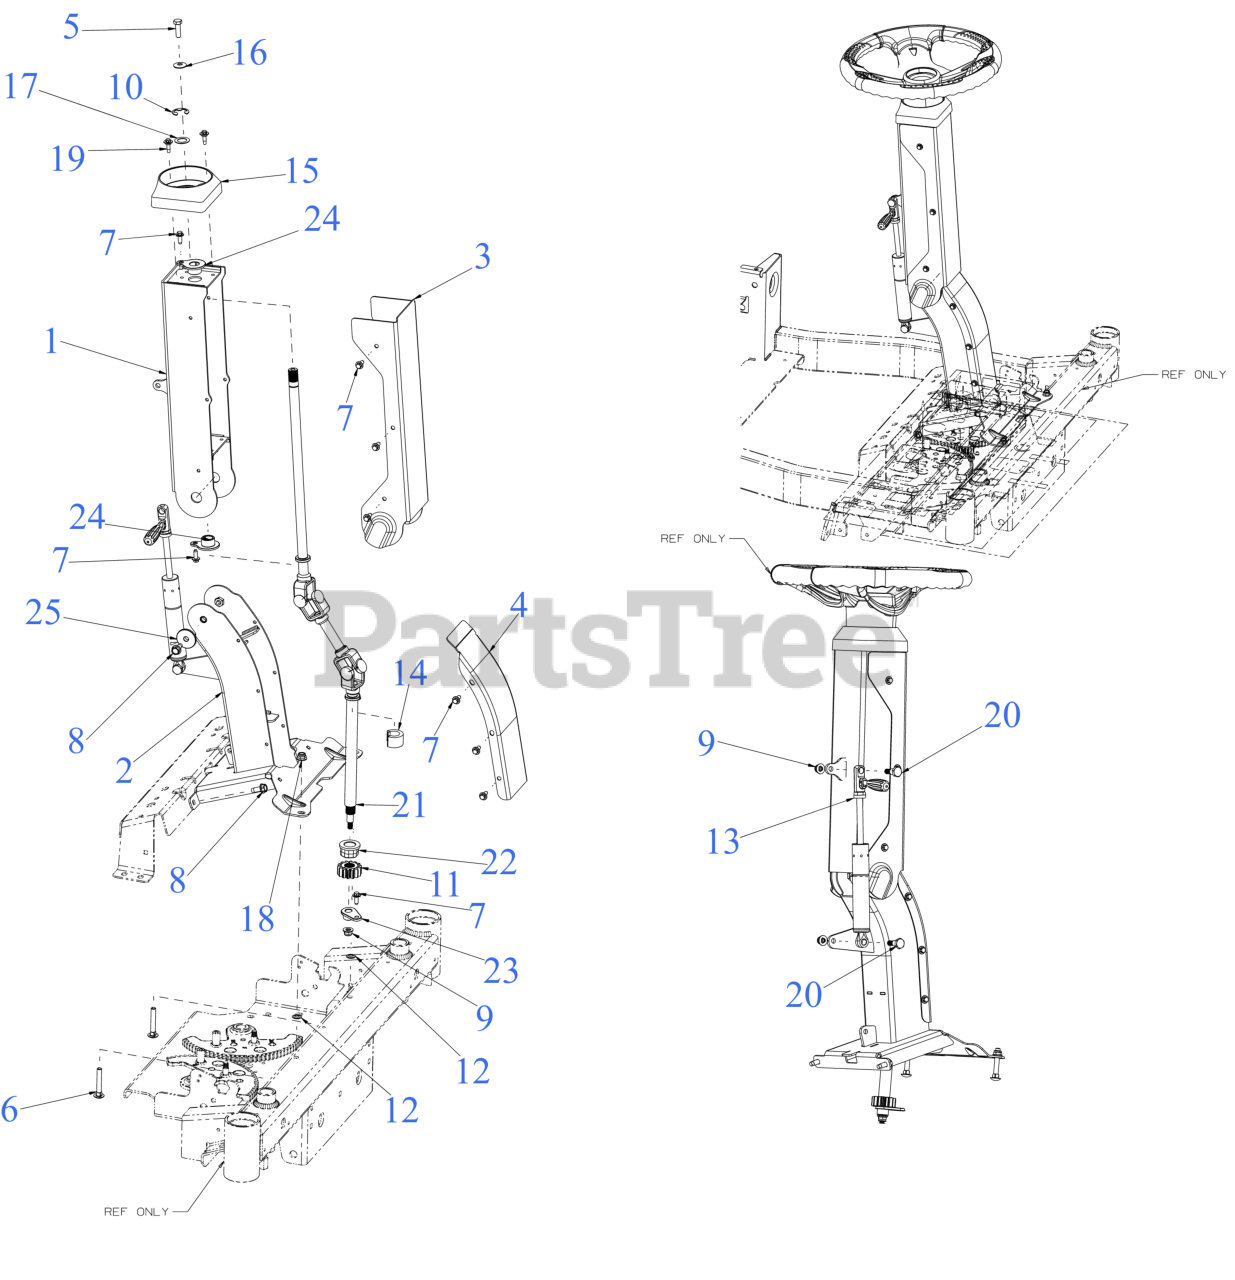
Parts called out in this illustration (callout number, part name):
1	STEERING COLUMN (UPPER)
2	STEERING COLUMN (LOWER)
3	COLUMN COVER (UPPER)
4	COLUMN COVER (LOWER)
5	HEX HEAD CAP SCREW 5/16-24 x 1.00 GR5
6	CARRIAGE BOLT 5/16-18 x 2.00 GR5
7	SCREW M6-1 x .625
8	SCREW 5/16-18 x .750
9	FLANGE LOCK NUT 5/16-18
11	STEERING GEAR 14T
13	STEERING TILT CYLINDER
14	SPACER: .76ID x .75
15	STEERING COLUMN CAP
16	BELL WASHER .337 X.867 x .057
17	FLAT WASHER
19	SHOULDER SCREW M6-1 .368 X.115
20	SHOULDER SCREW .393 X .505 LG
21	STEERING SHAFT
22	HEX FLANGE BEARING
23	FLANGE BEARING
24	FLANGE BEARING .628 ID
25	SHOULDER SPACER
